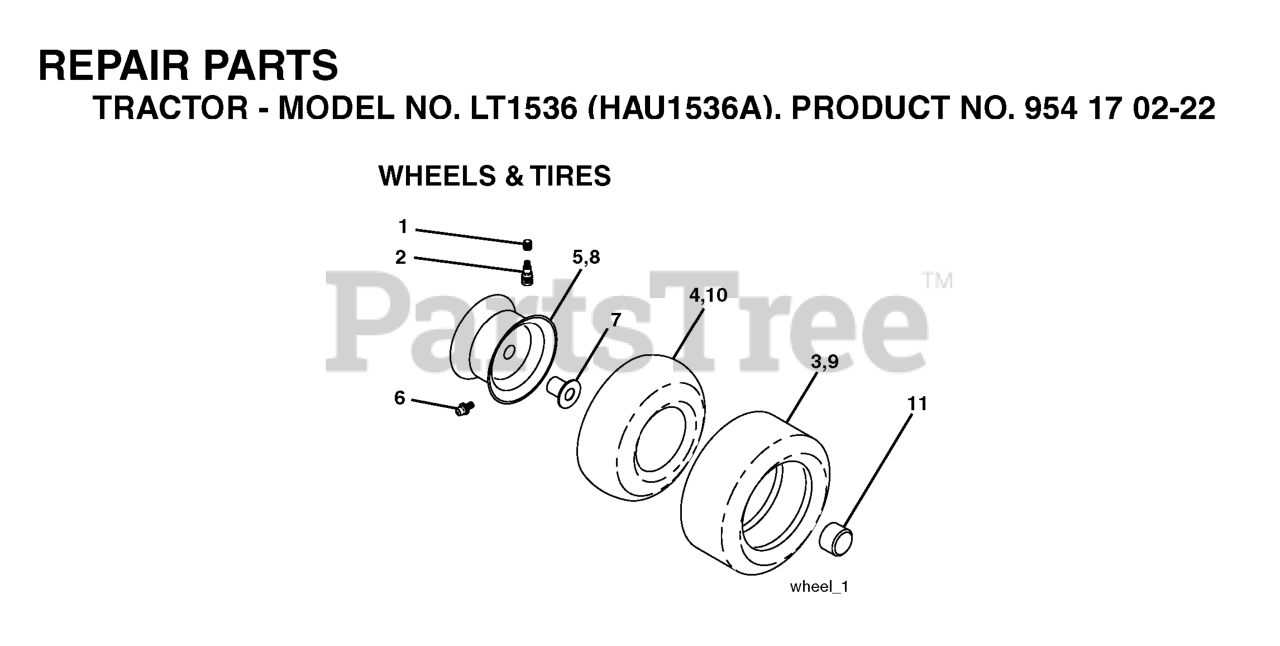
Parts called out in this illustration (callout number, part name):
2	VALVE STEM LT
3	TIRE HEAVY DUTY
4	TUBE.5.3/4.5/6
5	RIM ASM 6" FRONT SILVER
6	FITTING LT
7	BEARING T
8	RIM ASM 8" REAR SILVER
9	TIRE HEAVY DUTY
10	TUBE
11	CAP, AXLE BLK
